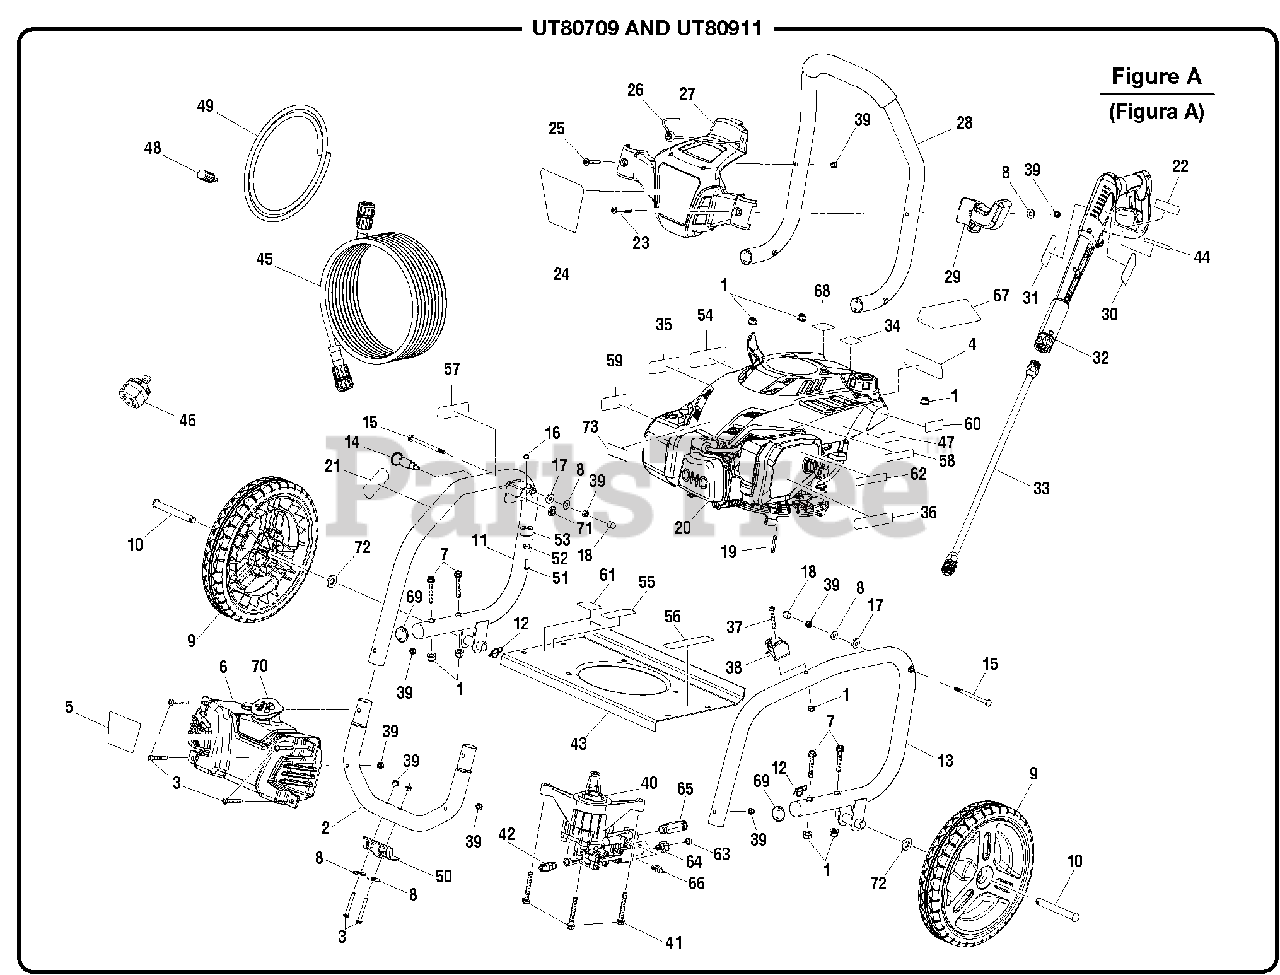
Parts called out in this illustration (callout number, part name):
2	Bolt (M6 x 25 mm)
3	Fuel Strainer
6	Fuel Tank
7	Fuel Filter
8	Fuel Valve
9	Fuel Hose
11	Main Frame Assembly (right)
12	Spring pin
13	Main Frame Assembly (left)
14	Handle Release Knob
15	Bolt (1/4-20 x 3.5 in.)
16	Flange Nut (M4 x 0.7 in.)
19	Output Shaft Key
20	Subaru 190cc Engine EPA
21	Hot Surface Label
22	Trigger Handle Warning Label
23	Screw (1/4-20 x 2.27 in.)
24	Performance Label
25	Screw (1/4-20 x 1.65 in.)
26	Bungee Cord Assembly
27	Hose Storage
28	Handle Assembly
29	Trigger Handle Holder
30	Trigger Handle Warning Label
31	Logo Label (Homelite)
32	Trigger Handle Assembly
33	Spray Wand
34	E85 Label
35	Danger Label
36	Engine Quick Start Label
37	Bolt (1/4-20 x 1.85 in.)
38	Spray Wand Holder
39	Lock Nut (1/4-20)
40	Pump (Incl. Key Nos. 63-66)
41	Bolt (M8 x 2.36 in.)
42	Thermal Release Valve
43	Engine Plate
44	Trigger Handle Spec Label
45	High Pressure Hose (25 ft.)
46	6-in-1 Change Over Nozzle
47	Release Water Label
49	Injection Hose
50	Rubber Foot
51	Bolt (M4 x 1/2 in.)
52	Washer (M4)
53	Rubber Bumper
54	Danger Label (French)
55	Data Label
56	Pump Quick Start Label
57	Combustion Warning Label
58	EMC Label
59	Hot Muffler Label
60	Choke Label
61	Oil Dipstick Label
62	Inquiries Label
63	Filter Screen
64	Inlet Tube
65	Outlet Tube
66	Detergent Suction Kit
67	Warning Hang Tag
68	Lubricant Label
70	Soap Tank Cap
71	Lock Nut (1/2-20)
72	Washer (1/2 in.)
73	Logo Label (Subaru)
